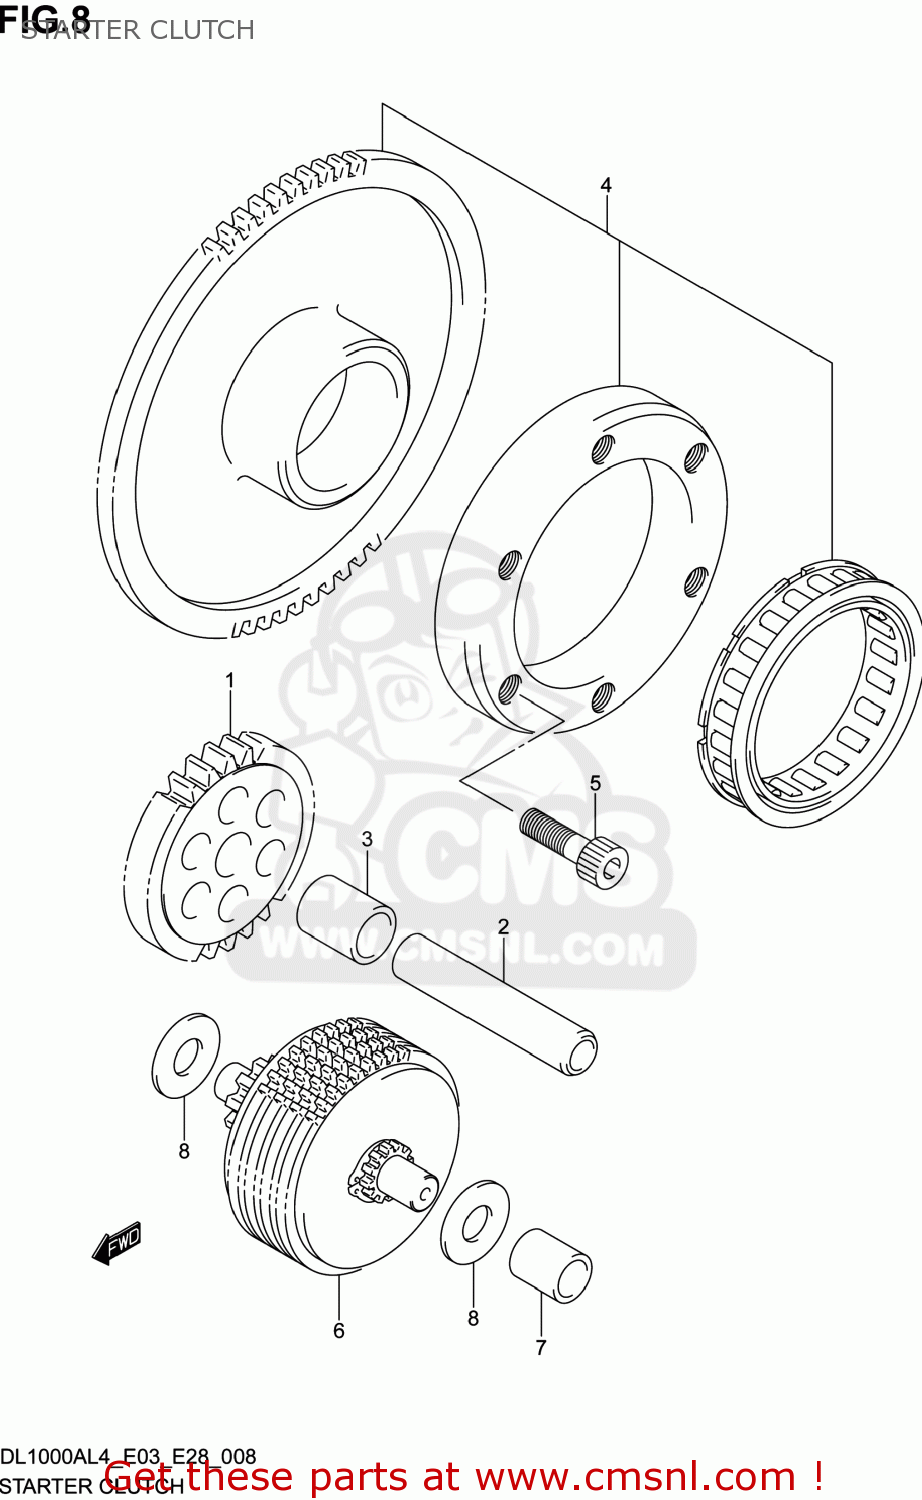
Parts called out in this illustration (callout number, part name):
1	GEAR,STARTER IDLE NO.2
2	PIN(7X12X50.5)
3	SPACER(12.5X19X17.5)
4	CLUTCH SET,STARTER
5	BOLT(8X20)
6	LIMITER ASSY,START ID GR NO.1
7	BUSH,LIMITER GEAR SHAFT
8	SHIM(10X20X1)
